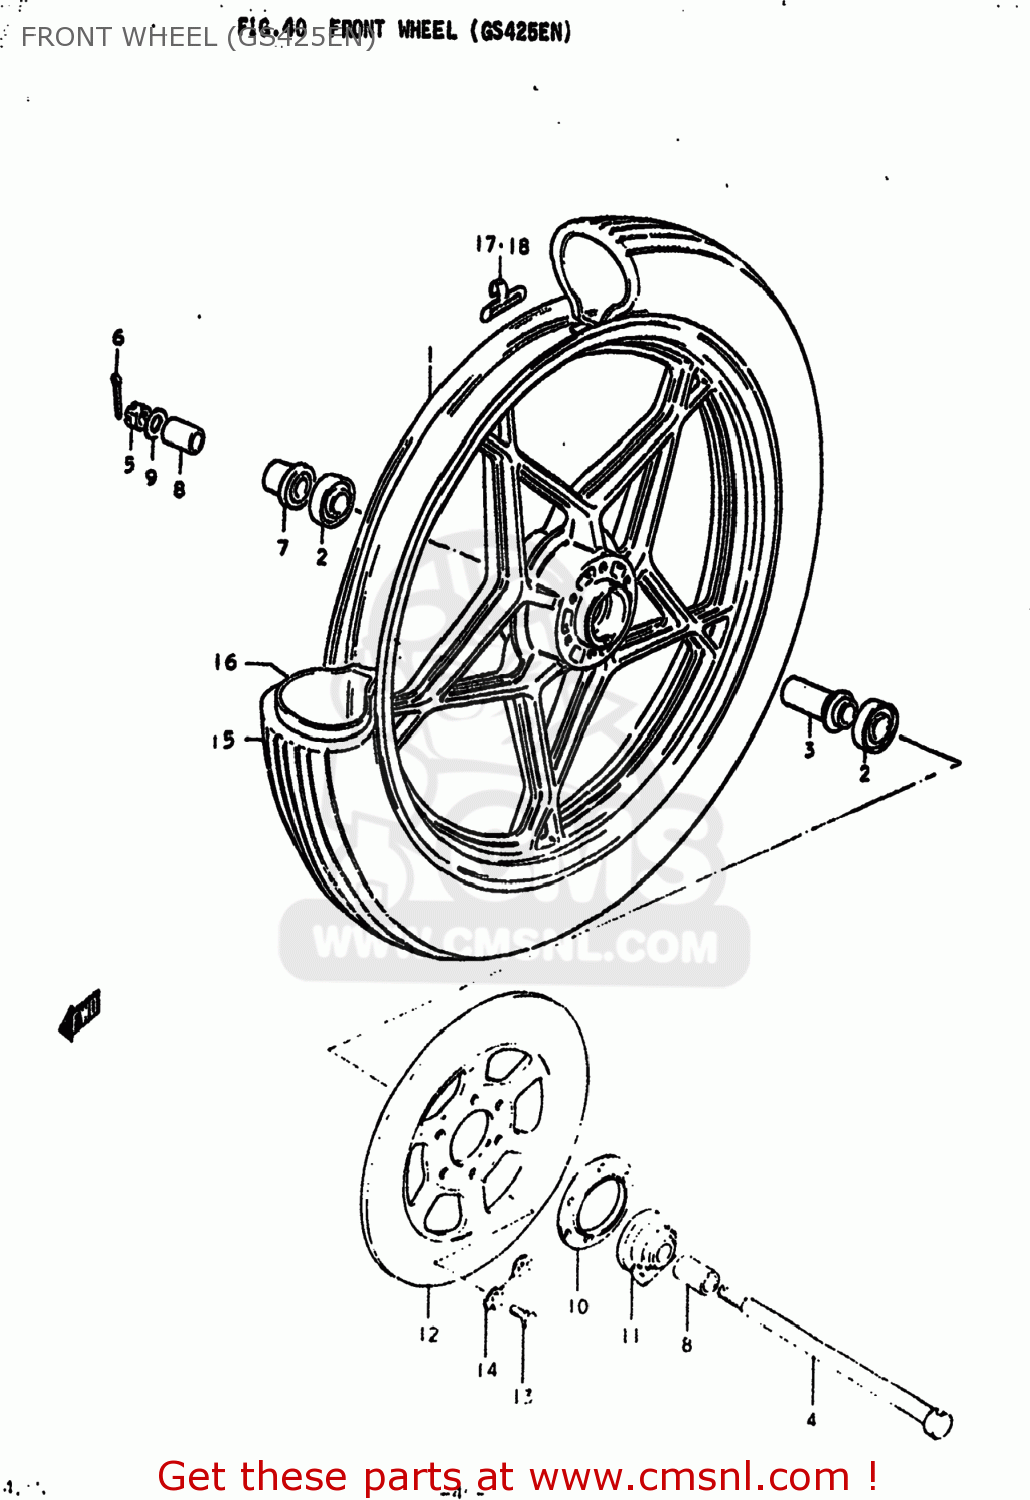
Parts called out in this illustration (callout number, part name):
1	WHEEL (DARK GRAY)
2	BEARING
3	SPACER(15.3X21.7X63)
4	AXLE,FRONT
5	NUT 12MM
6	COTTER PIN
7	SPACER,FR AXLE,R
8	SPACER(15X22X30)
9	WASHER
10	DUST SEAL,SPEEDOMETER GEAR BOX
11	BOX ASSY,SPEEDOMETER GEAR
12	DISC,REAR BRAKE
13	BOLT(8X25)
14	WASHER
15	TIRE,FRONT
16	TUBE,INNER
17	BALANCER,WHEEL
18	BALANCER,WHEEL
